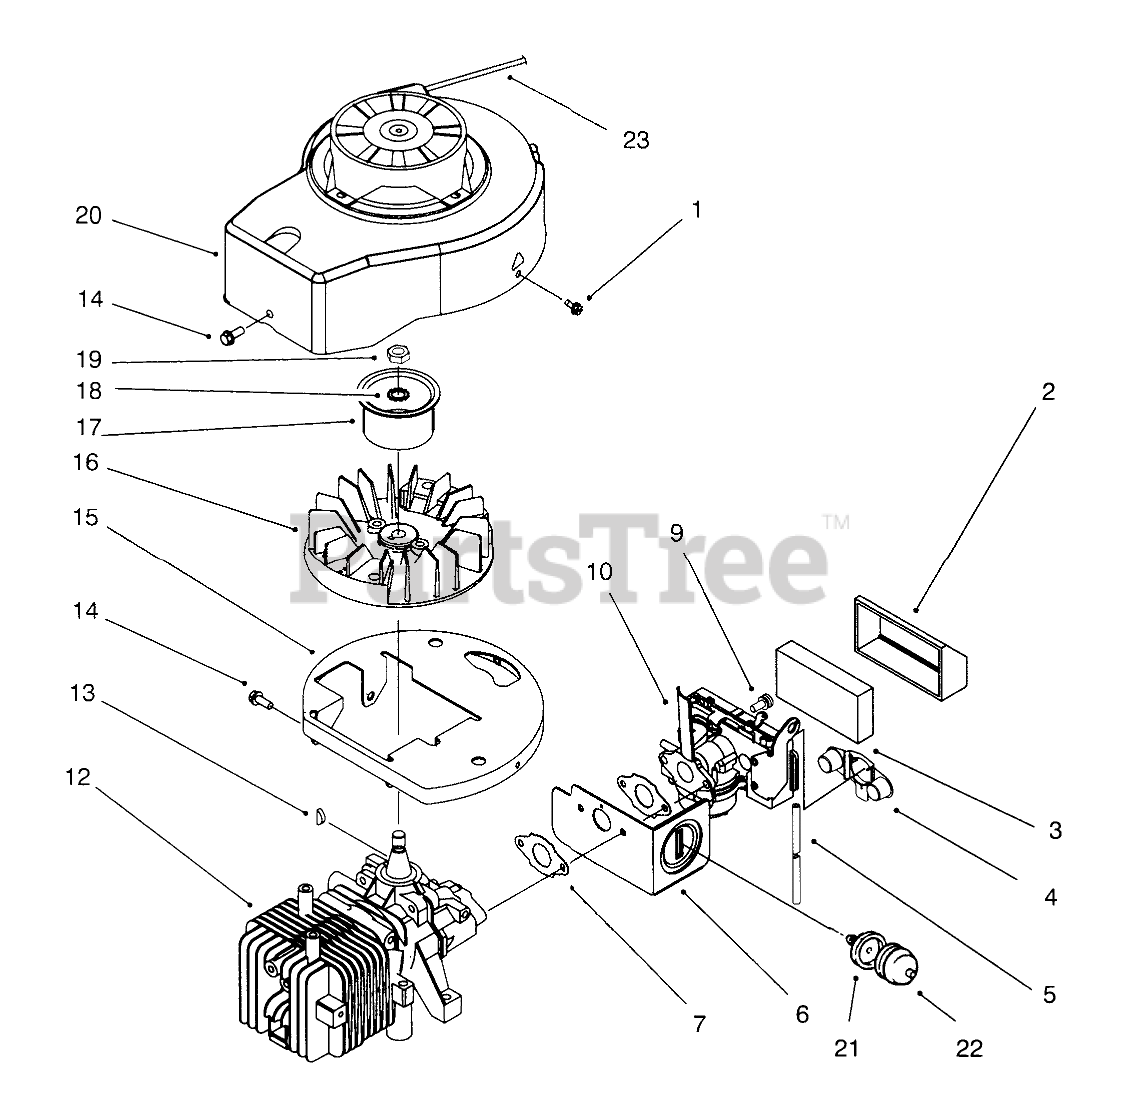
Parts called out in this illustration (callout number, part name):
1	SCREW VF
2	COVER-AIR FIL. V
3	ELEMENT-AIR FIL VF
4	SHIELD-FUEL V
5	HOSE-PRIMER
6	SHIELD - CARB. V
7	GASKET-CARB VF
9	SCREW
10	CARBURETOR ASM
12	SHORT BLOCK
14	SCREW
15	Base-Shroud
16	FLYWHEEL(MACH) V
17	HUB-STARTER V
18	WASHER-LOCK
20	SHROUD/START
21	BODY-PRIMER
22	BULB-PRIMER
23	SHROUD
